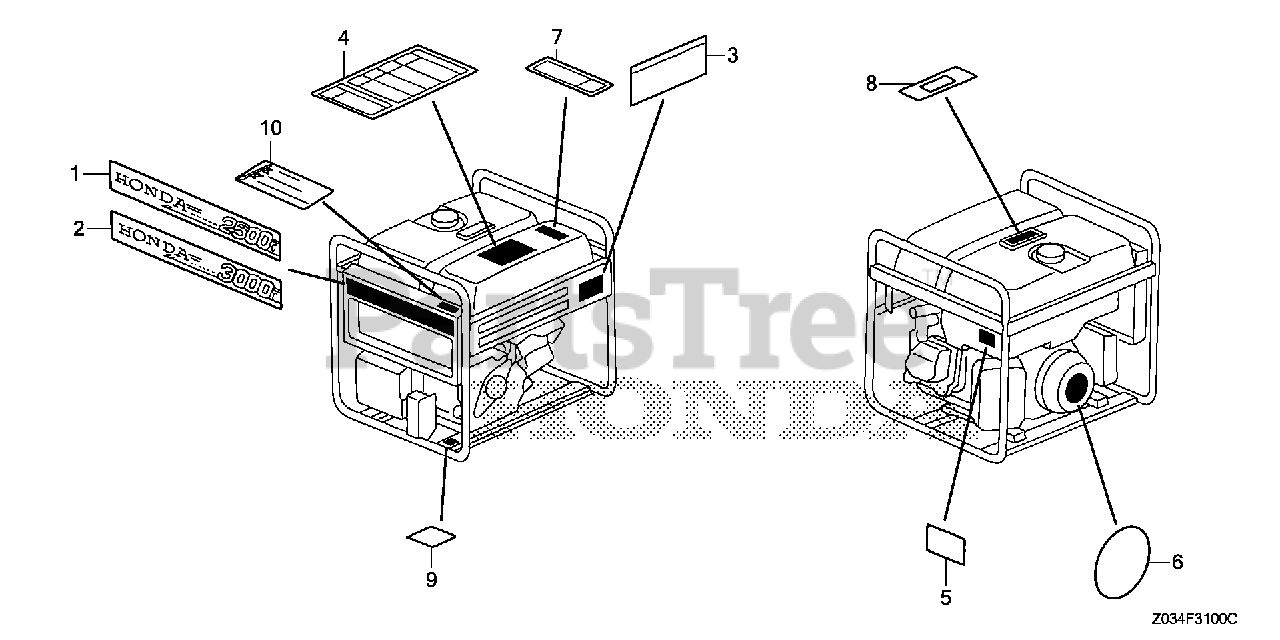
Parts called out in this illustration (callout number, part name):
2	EMBLEM (EB3000C)
3	MARK, SPECIFICATION
4	LABEL, OPERATOR WARNING
5	MARK, CHOKE
6	MARK, CYCLOCONVERTER
7	MARK, EX. CAUTION
8	PLATE, FUEL INDICATION
9	MARK, OIL CAUTION
